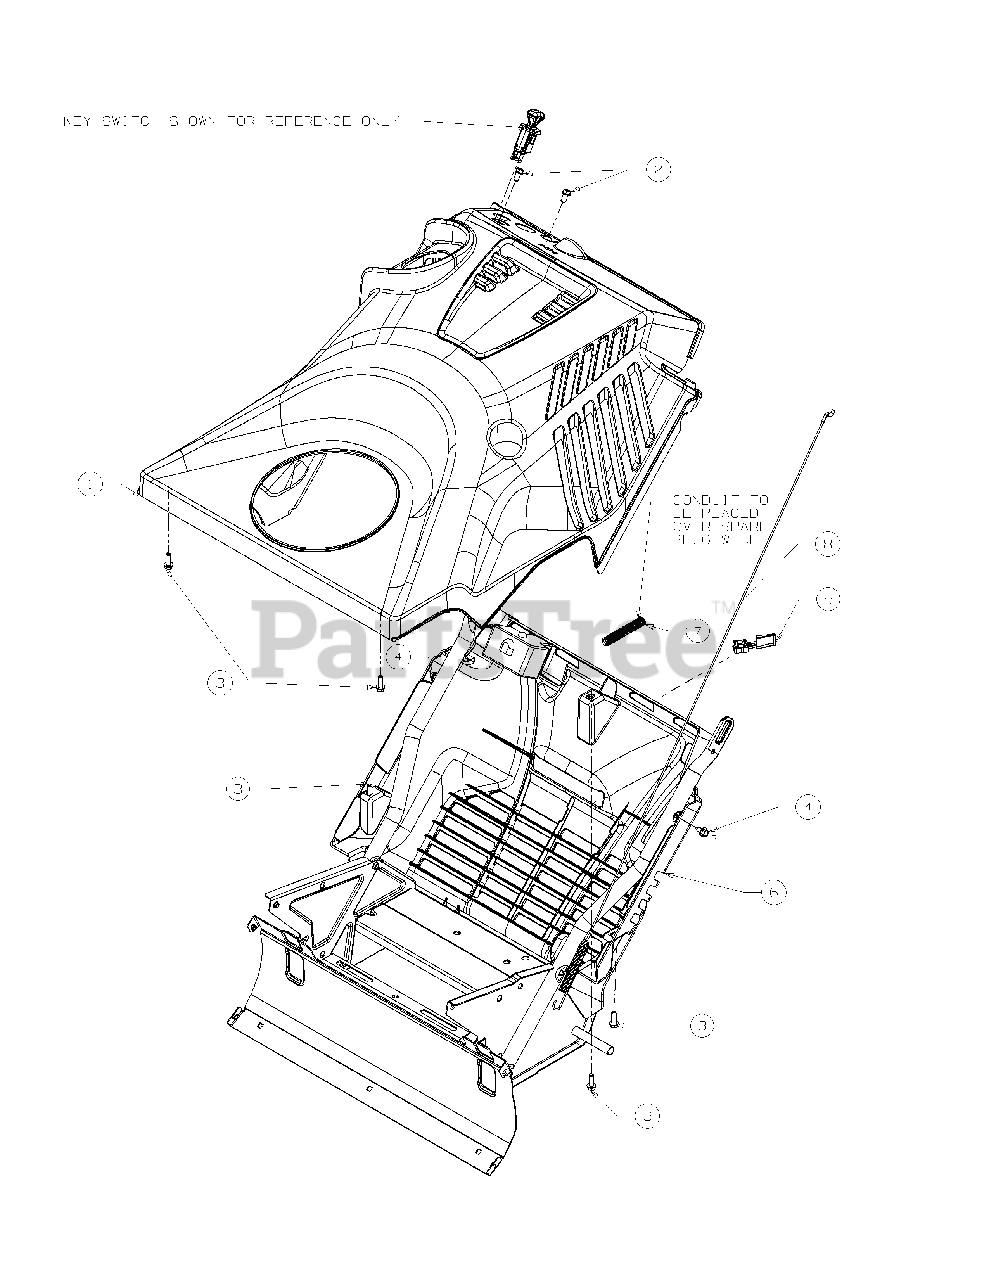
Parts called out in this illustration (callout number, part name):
1	Kit-Service Snow
2	Screw-Hex
3	Screw-Hex Tap 1/4
4	Screw Hex.Wash.Hd
5	Lever-Choke Extenion
6	Cover-Snwth Bo
7	Conduit-Convoluted
8	Cable-Auger Clu
